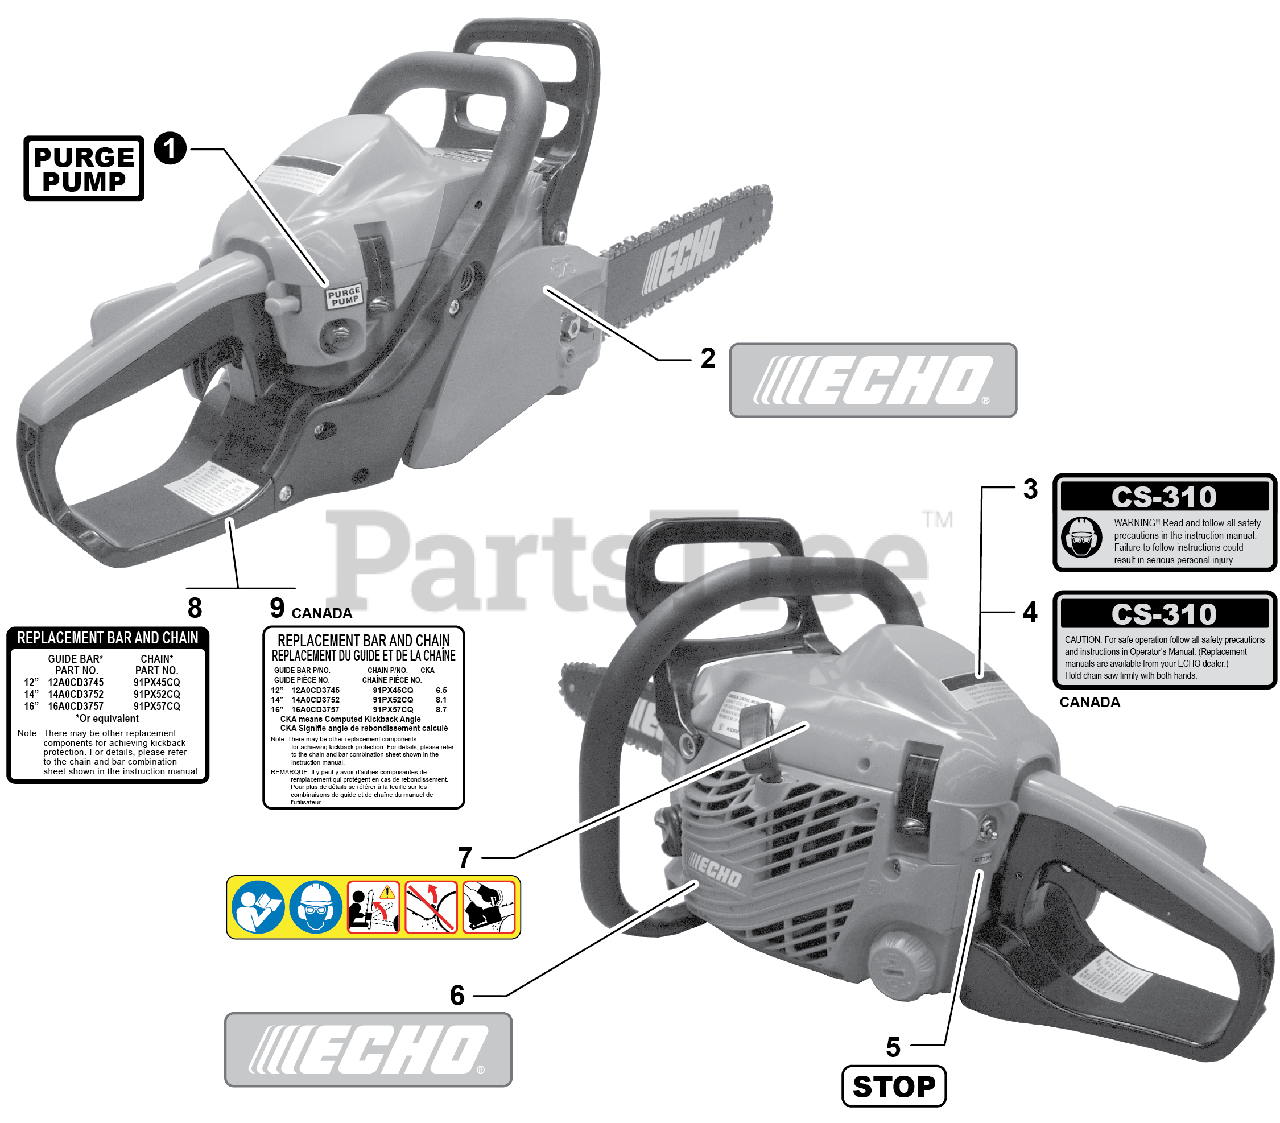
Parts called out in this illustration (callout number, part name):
1	LABEL, PURGE PUMP
2	LABEL, ECHO
3	LABEL, MODEL CS-310
4	LABEL, MODEL CS-310
5	LABEL, STOP
6	LABEL, ECHO
7	LABEL, CAUTION
8	LABEL, BAR & CHAIN
9	LABEL, BAR & CHAIN
